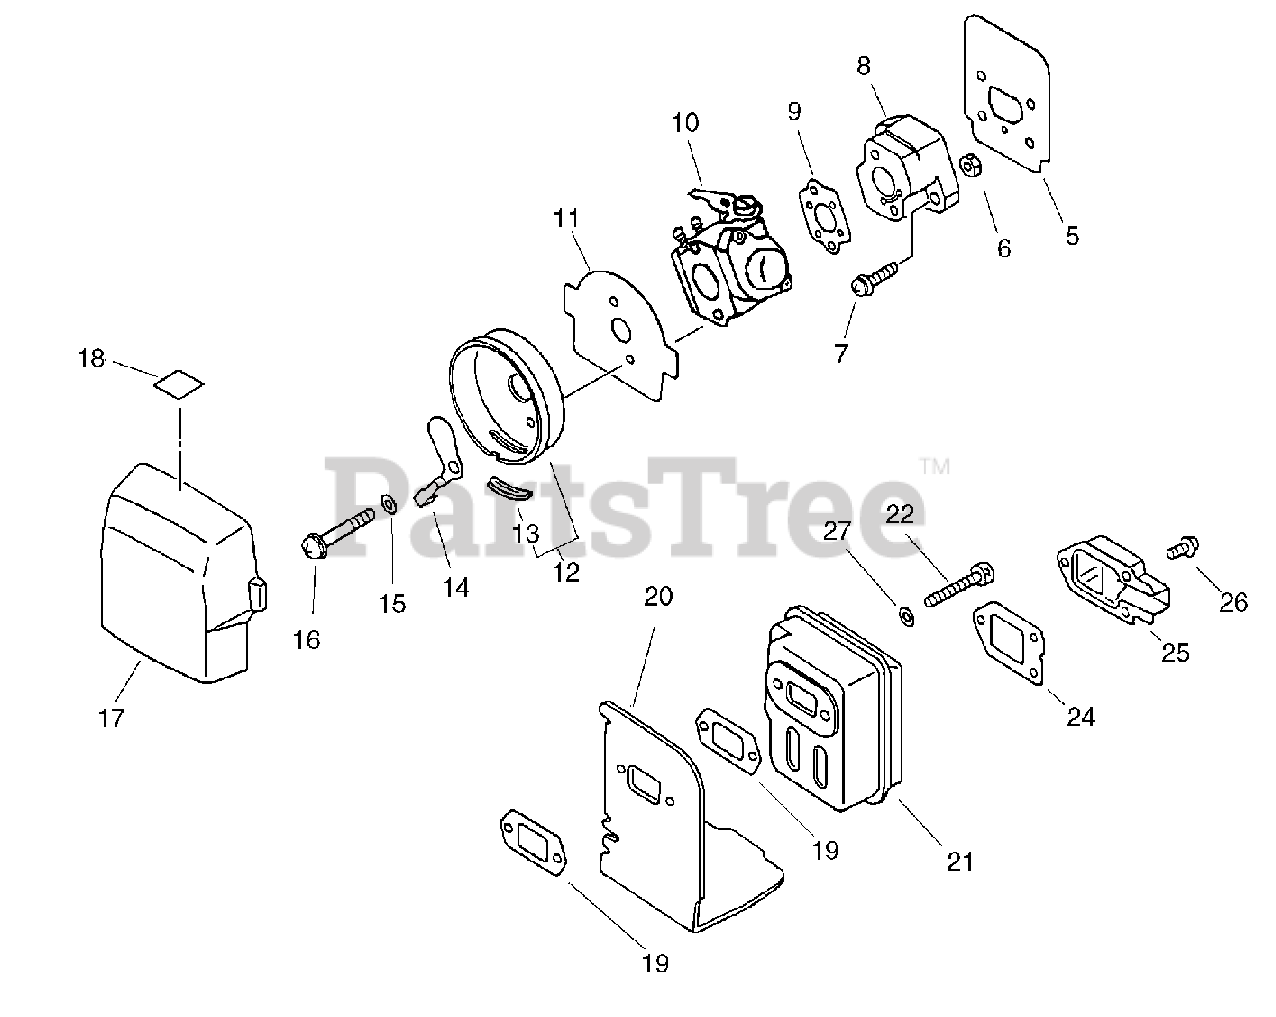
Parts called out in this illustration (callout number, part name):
5	Gasket,Intake
6	Nut 5
7	Screw 5*20
8	Insulator, Intake
9	Gasket, Intake
10	Carburetor C1U-K9A
11	Fixture,Air Cleaner
12	Case, Air Cleaner
13	Grommet, Choke
14	Shutter, Choke
16	Screw 5*57
17	Filter, Air
18	Label, Adjusting
19	Gasket,Exhaust
20	Cover,Muffler
22	Bolt, H.S. 5*55
24	Gasket, Muffler Lid
25	Lid, Muffler
26	Screw 4*10
